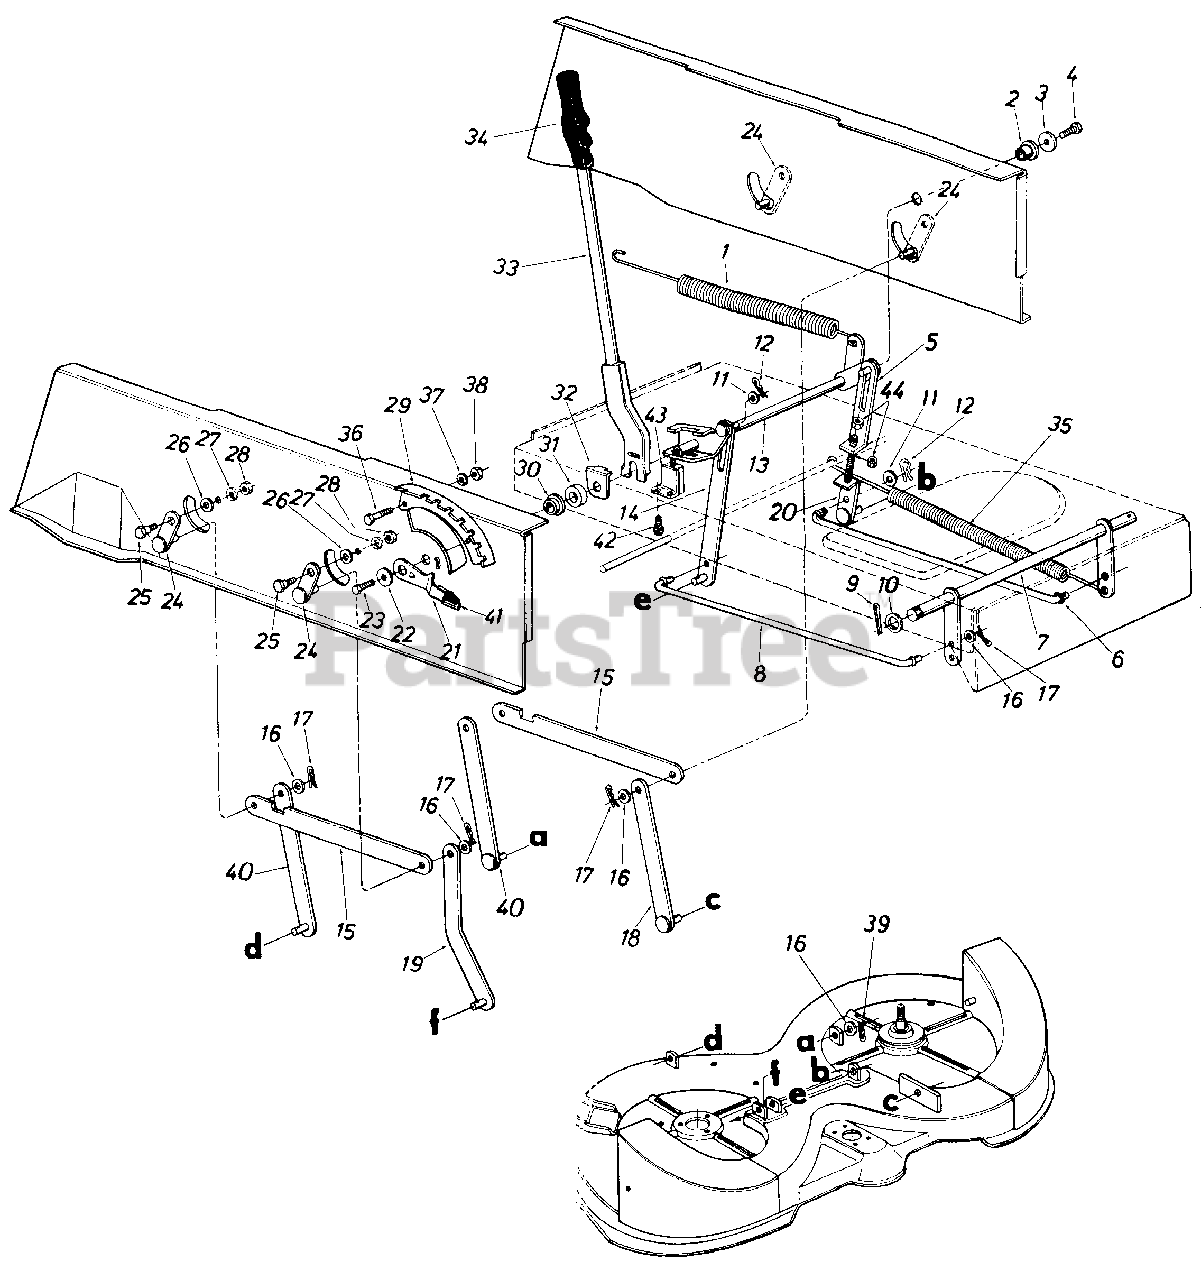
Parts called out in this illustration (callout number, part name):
1	Extension Spring .99" O.D. x 11.00" Lg.
2	Flange Bearing .634" I.D.
3	Fl-Wash. .344" I.D. x 1.125" O.D. x .125
4	Hex Wash. Hd. Self-Tap Scr. 5/16-18 x .62" Lg.
5	Adj. Link Lift
6	Stabilizer Rod
7	Stabilizer Shaft Ass'y.
8	Stabilizer Rod
9	Cotter Pin 1/8" Dia. x 1-1/4" Lg.
10	Fl-Wash. .635" I.D. x 1.12"O.D.
11	Fl-Wash. .531" I.D. x .940"O.D.
12	Inter. Cotter Pin .50" Dia.
15	Connecting Rod
16	Fl-Wash. .40" I.D. x .88" O.D.
17	Inter. Cotter Pin For 3/8" Rod
18	Link Deck Hanger Ass'y.
19	Link Deck Hanger Ass'y.
20	Adj. Link Lift Ass'y.
21	Deck Lift-Down Stop
22	Fl-Wash. .344" I.D. x 1.125" O.D. x .125
23	Hex Wash. Hd. Self-Tap Scr. 5/16-18 x .62" Lg.
24	Pivot Link Ass'y.
25	Shld. Bolt .437" Dia. x .180" Lg. (5/16-18)
26	Fl-Wash. .344" I.D. x .62"O.D.
27	L-Wash. 5/16" I.D.*
28	Hex Nut 5/16-18 Thd.
29	Index Brkt.
30	Flange Wash. .628" I.D. x 1.25" O.D.
31	RubberWash. 1.50" O.D. x .63" I.D. x .60
32	Retainer Washer-Lift Handle
33	Lift Handle Ass'y.
34	Grip
35	Extension Spring .99" O.D. x 13.25" Lg.
36	Hex Bolt 5/16-18 x .75" Lg.
37	L-Wash. 5/16" I.D.
38	Hex Nut 5/16-18 Thd.
39	Inter. Cotter Pin
40	Link Deck Hanger Ass'y.
41	Knob
42	Hex AB-Tap Scr. #10 x .50" Lg.
43	Safety Switch
44	Hex Jam Nut 3/8-16 Thd.
